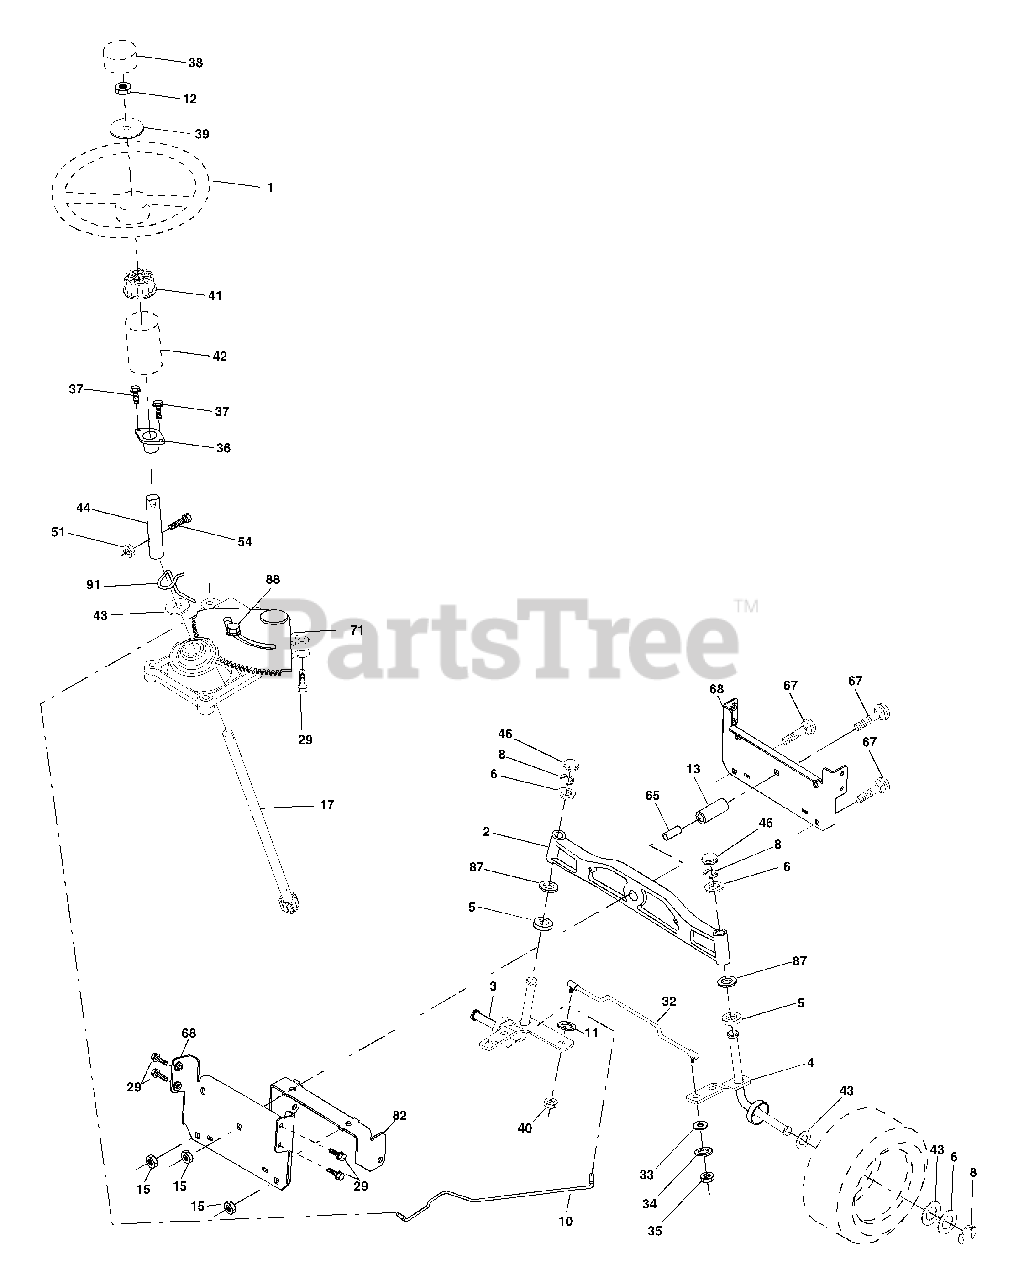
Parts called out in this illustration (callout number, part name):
1	Wheel Steering
2	Axle Cast LT Machined
3	Spindle Asm Cast LH
4	Spindle Asm Cast RH
5	Bearing Race Thrust Harden
6	Washer 25/32 X 1-5/8 X 16 Ga
8	Ring Klip #t5304-75
11	Washer Lock Hvy Hlcl Spr 3/8
12	Nut Hex Jam Toplock 1/2-20 UNF
13	Spacer Brg Axle Front
15	Nut Hex Flange Lock Yel D
17	Shaft Asm Steering
29	Screw 3/8-16x3/4
33	Washer 11/32 x 3/4 x 16 Ga.
34	Washer Lock Hvy. Helical 5/16 SD
35	Nut Crown Lock 5/16-24
36	Bushing Strg
37	Screw TT #32.5 x 5 x 3/8 Flange
38	Cap Wheel Steer
39	Washer 9/16 ID x 2-3/8 OD 12 Ga.
40	Nut Lock Center 3/8-24 Unf
41	Adaptor Wheel Strg
42	Boot Dash Steering
43	Washer 25/32 X 1 1/4 X 16 Ga
44	Extension Steering Non-adjust
46	Cap Spindle Fr Top Blk
51	Nut Crownlock 1/4-28
54	Bolt Hex 1/4-28 UNF x 1-1/4 Gr. 8
65	Spacer, Brace Axle
67	Bolt Rdhd 3/8-16 x 2-1/4
68	Brace, Axle
71	Steering Asm.
82	Bracket Susp Chassis Front 15"
87	Washer Flat .781 x 1-1/2 x .14
88	Bolt Shoulder 7/16-20
91	Clip, Steering
